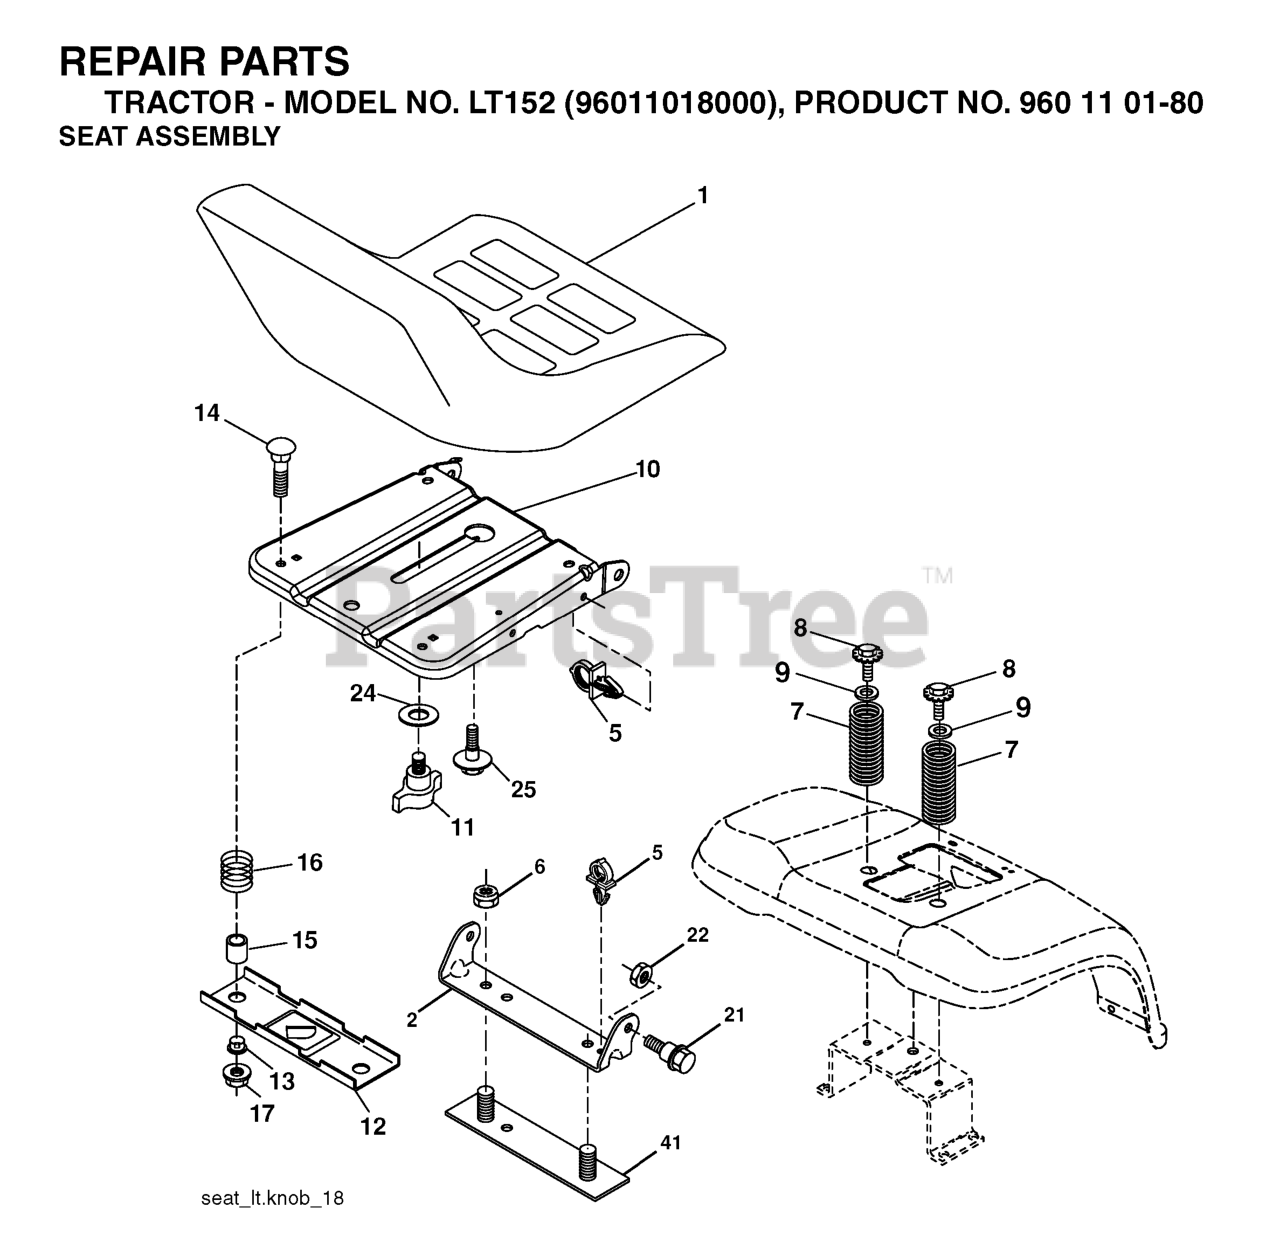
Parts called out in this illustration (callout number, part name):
1	SEAT
2	SEAT PIVOT BRKT
3	BOLT, HEX 3/8-16X1
6	NUT
7	SPRING COMPRESSION
8	SCREW 3/8-16X1
9	WASHER
10	PAN.ASM.SEAT.1SLOT
11	KNOB.SEAT.ADJ.WINGNUT
12	BRKT.MNTNG.SWITCH.SEAT.BLACK
14	BOLT.ROUND.HEAD.SQUARE.NECK
15	SPACER SPLIT 28X.96
17	NUT T
21	BOLT.SHOULDER.5/16-18
22	NUT.71038.31-18.HEX.NYLOCK
25	BOLT,SHOULD
41	STRAP
